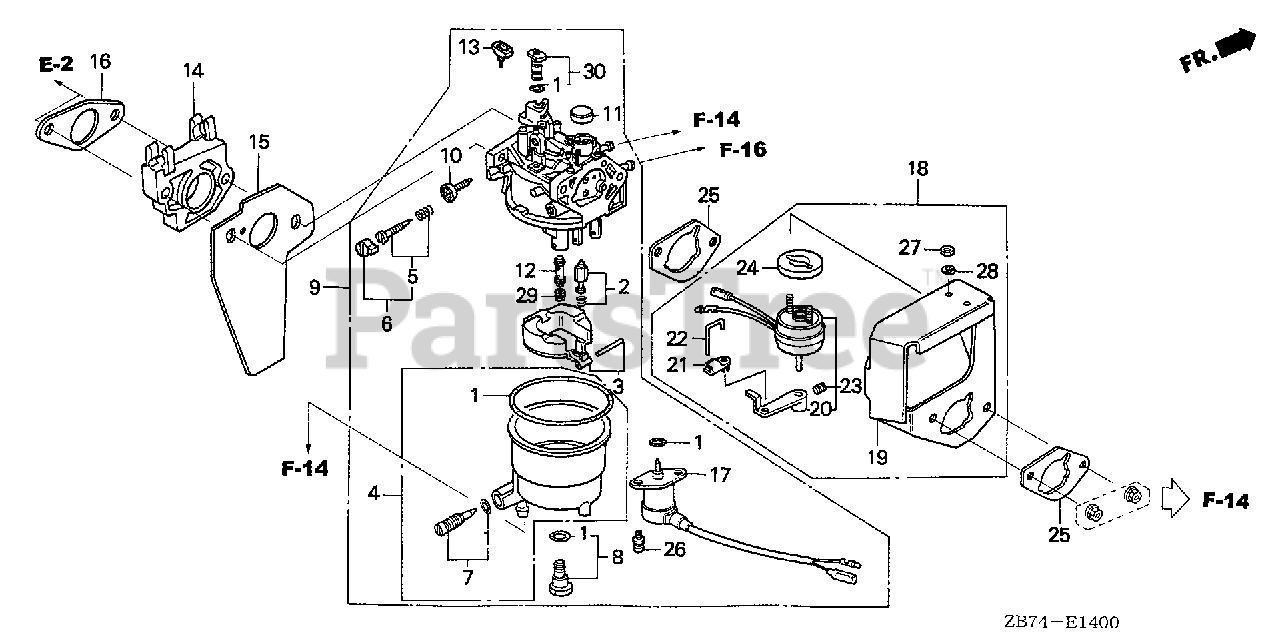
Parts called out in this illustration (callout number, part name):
1	GASKET SET
2	VALVE SET, FLOAT
3	FLOAT SET
4	CHAMBER SET, FLOAT
6	SCREW SET (Honda Code 4219879). (CARBURETOR NO.)
7	SCREW SET, DRAIN (ADVENTURE GREEN) (CARBURETOR NO.)
8	SCREW SET B
9	CARBURETOR ASSY.
10	SCREW, THROTTLE STOP
11	CAP, CHOKE LEVER DUST
12	NOZZLE, MAIN
13	COLLAR, SET
14	INSULATOR, CARBURETOR
15	GASKET, CARBURETOR
16	GASKET, INSULATOR
17	VALVE ASSY., SOLENOID
18	STAY ASSY., SOLENOID
19	STAY, CHOKE SOLENOID
20	LEVER, CHOKE SOLENOID
21	JOINT, ROD
22	ROD, CHOKE SOLENOID
23	SOLENOID ASSY., CHOKE
24	SPACER, CHOKE SOLENOID
25	GASKET, AIR CLEANER
26	SCREW-WASHER (5X12)
27	NUT, HEX. (3MM)
28	WASHER, SPRING (3MM)
29	JET, MAIN (#75) (CARBURETOR NO.)
29	JET, MAIN (#78) (CARBURETOR NO.)
29	JET, MAIN (#80)
30	JET SET, PILOT (#45)
